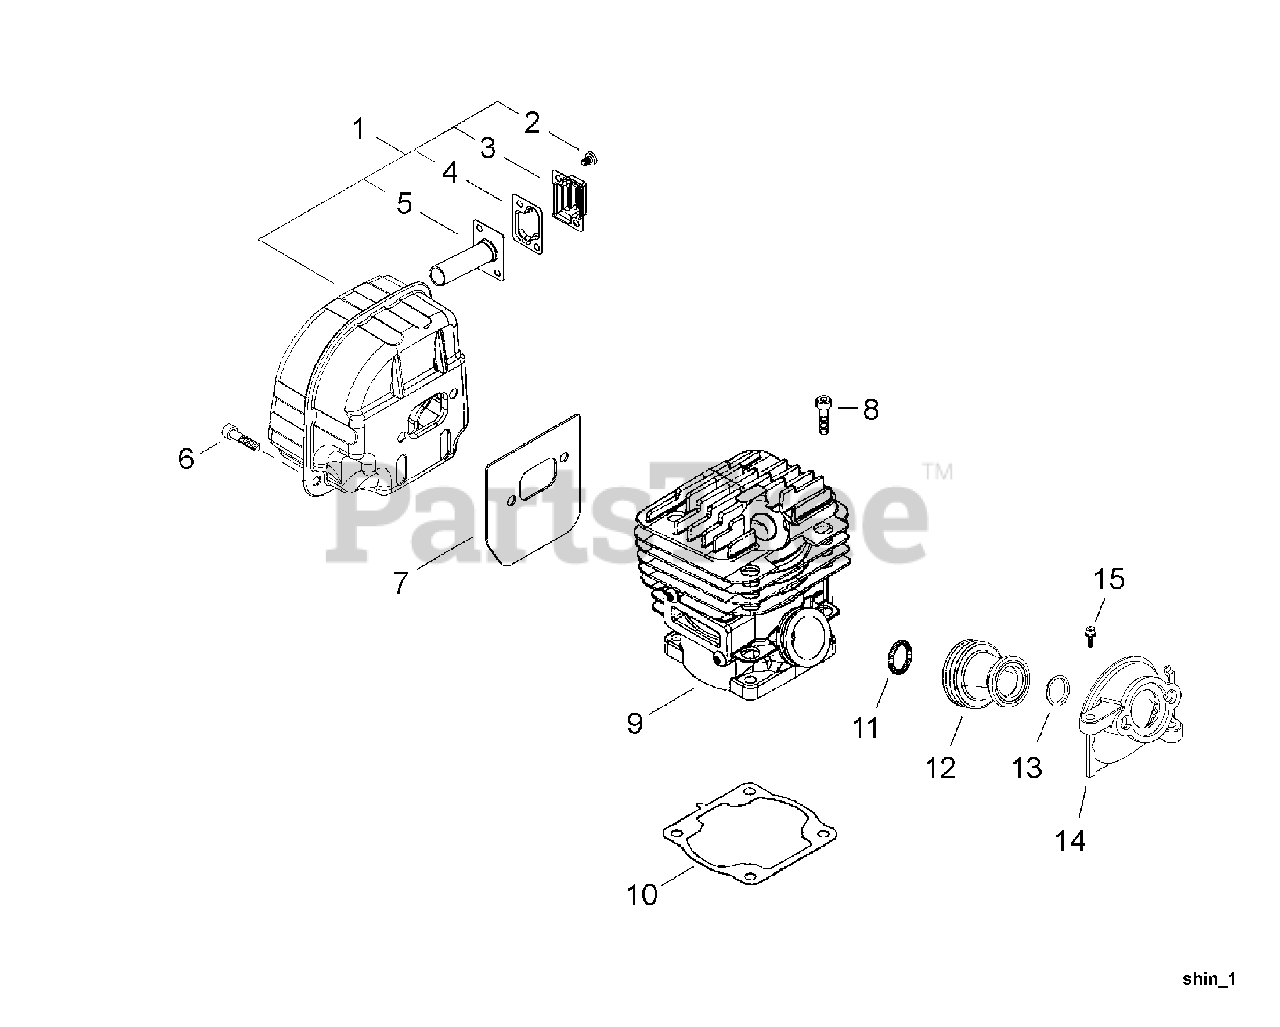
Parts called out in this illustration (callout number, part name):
1	MUFFLER ASSY
2	SCREW M4×6
3	COVER, SPARK ARRESTER
4	SCREEN, SPARK ARRESTER
5	PIPE, EXHAUST
6	BOLT M5×18
7	HEAT SHIELD, EXHAUST
8	BOLT M5×18
9	CYLINDER ASSY
10	GASKET, CYLINDER
11	SPRING
12	BELLOWS, INTAKE
13	COLLAR 16
14	ADAPTOR, INTAKE
15	BOLT M4×16
